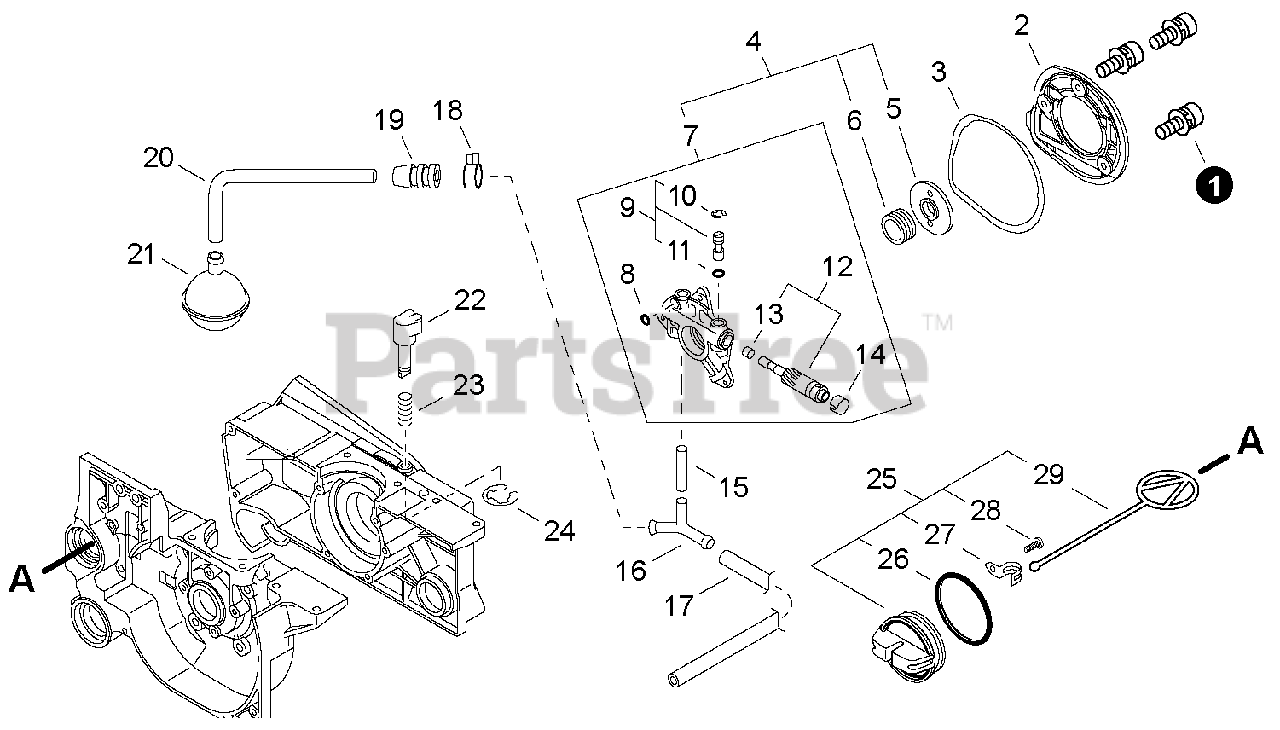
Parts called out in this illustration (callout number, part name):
1	SCREW - 4X12
2	COVER, OILER
3	GASKET, OILER COVER
4	AUTO-OILER KIT
5	WASHER - 12
6	GEAR - WORM
7	AUTO-OILER ASSY
8	O-RING - 3
9	CONTROL PIN ASSY
10	RING, RETAINING
12	PLUNGER KIT
14	CAP, PLUNGER
15	PIPE - 3X6X20 -- BLACK
16	CONNECTOR, PIPE
17	PIPE - 3X6X200 -- BLACK
18	CLIP - 6.5
20	PIPE - OIL
21	FILTER, OIL
22	DIAL, AUTO-OILER
24	RING, RETAINING - 3
25	CAP ASSY
26	O-RING - 25
27	RETAINER
28	SCREW - 3X8 -- TAPPING
29	CONNECTOR, CAP
